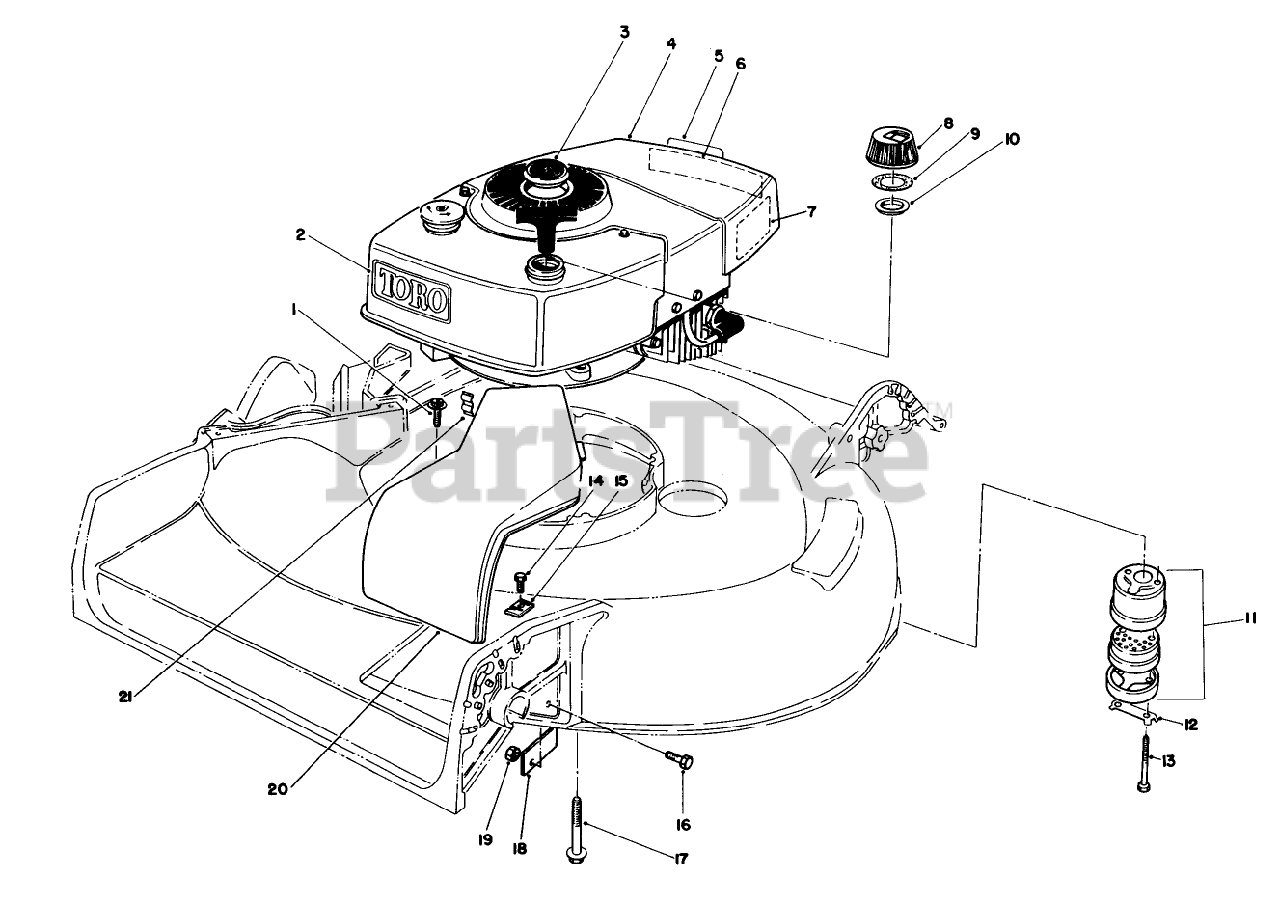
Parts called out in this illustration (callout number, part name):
1	SCREW
4	Engine
9	GASKET
11	MUFFLER ASM
12	CLIP - LOCKING
13	SCREW-HH
14	SCREW-THD ROLL, HWH
16	SCREW-HH
17	3/8-16 X 2-3/4 CAPSCR
19	NUT-LOCK, NI
